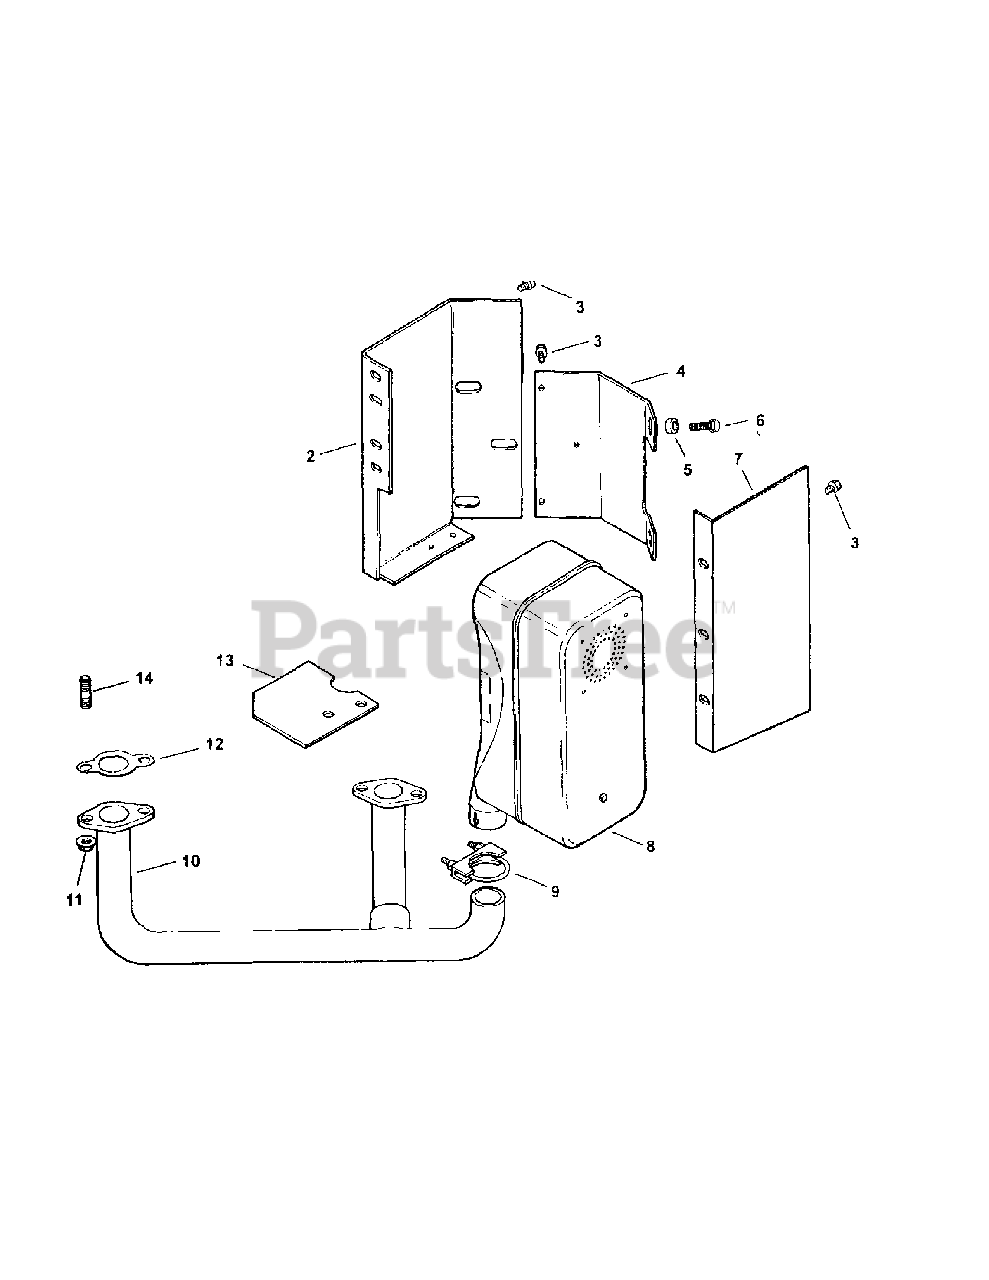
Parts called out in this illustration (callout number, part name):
1	Kit, Muffler Mounting, Oil Filter Side
2	Bracket, Muffler, Oil Filter Side
3	Screw, Hex Flange
4	Bracket, Muffler
5	Spacer
6	Screw, Hex Flange
7	Deflector, Heat
9	Clamp, Muffler
10	Manifold, Exhaust #2 Side
11	Nut, Hex Flange
12	Gasket, Exhaust
13	Deflector, Heat
14	Stud
